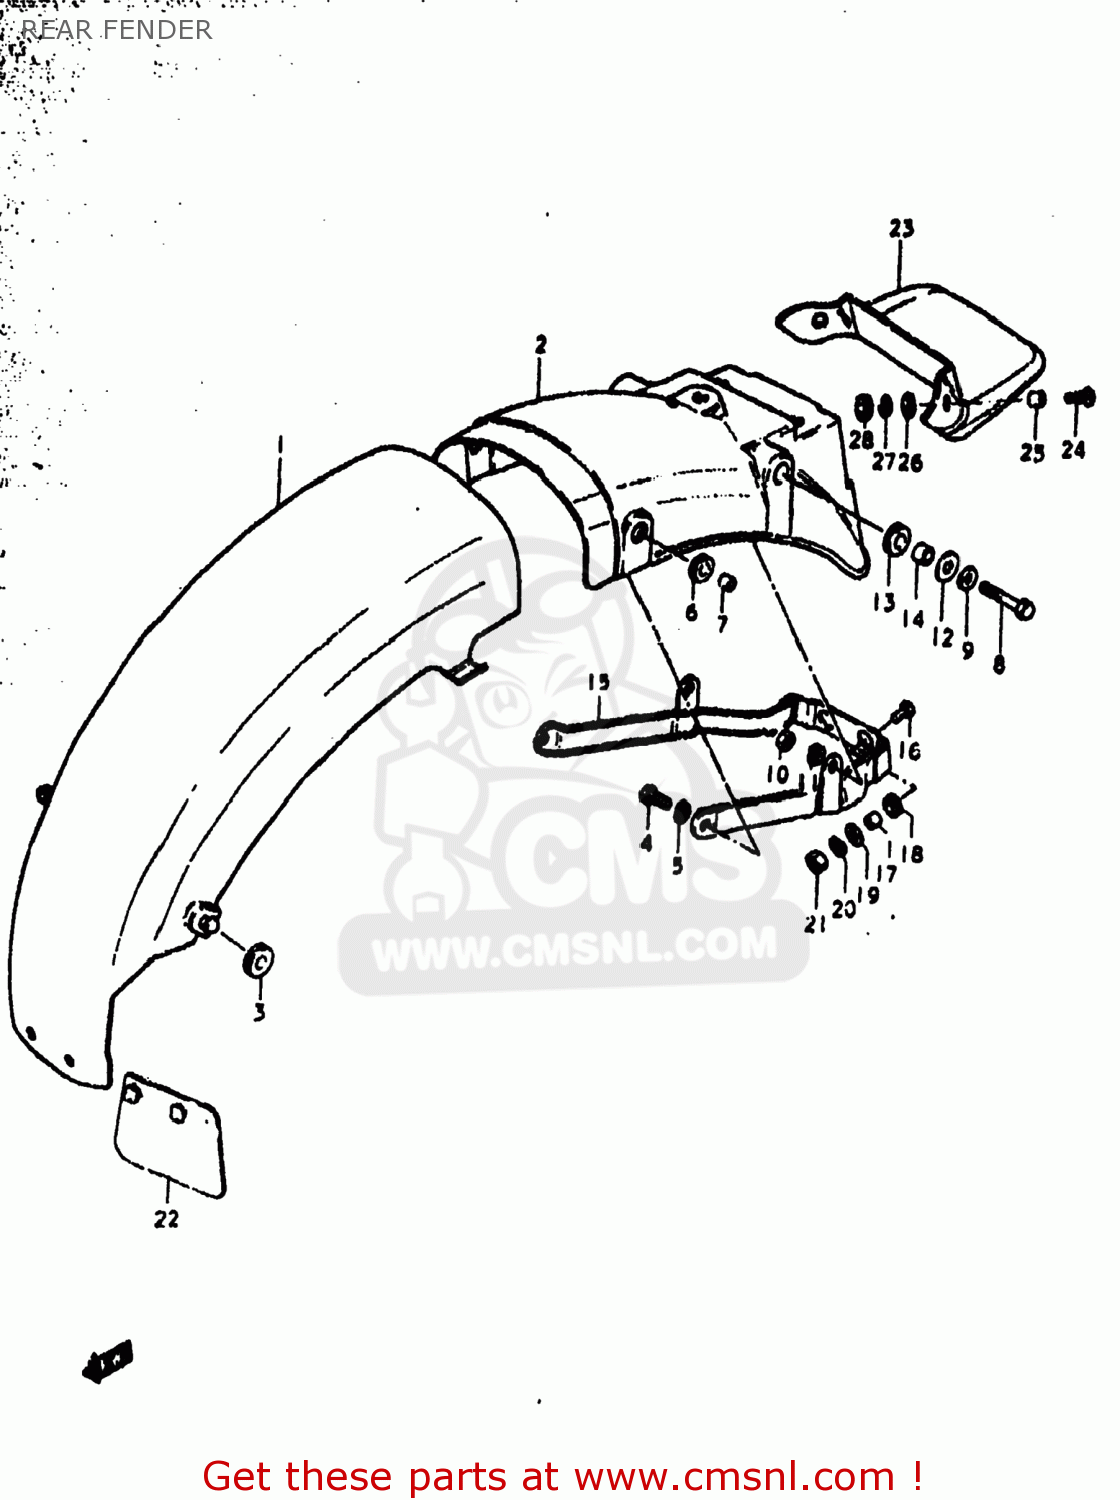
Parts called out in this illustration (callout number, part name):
1	FENDER,REAR
2	BODY,RR FENDER RR
3	CUSHION
4	BOLT
5	LOCK WASHER
6	CUSHION
7	SPACER(6.1X9X7.5)
8	BOLT
9	WASHER
10	NUT
11	LOCK WASHER
12	WASHER(8.5X26X1.2)
13	CUSHION
14	SPACER (8.2X12X7.5)
15	REINFORCEMENT,REAR FENDER
16	SCREW
17	SPACER (6.1X9X9)
18	CUSHION
19	WASHER(6,5X22X1.6)
20	LOCK WASHER
21	NUT
22	GUIDE,RR FENDER MUD
23	EXTENSION,REAR FENDER
24	SCREW (6X15)
25	SPACER(6.2X8.3X5.7)
26	WASHER
27	LOCK WASHER
28	NUT
29	NUT
